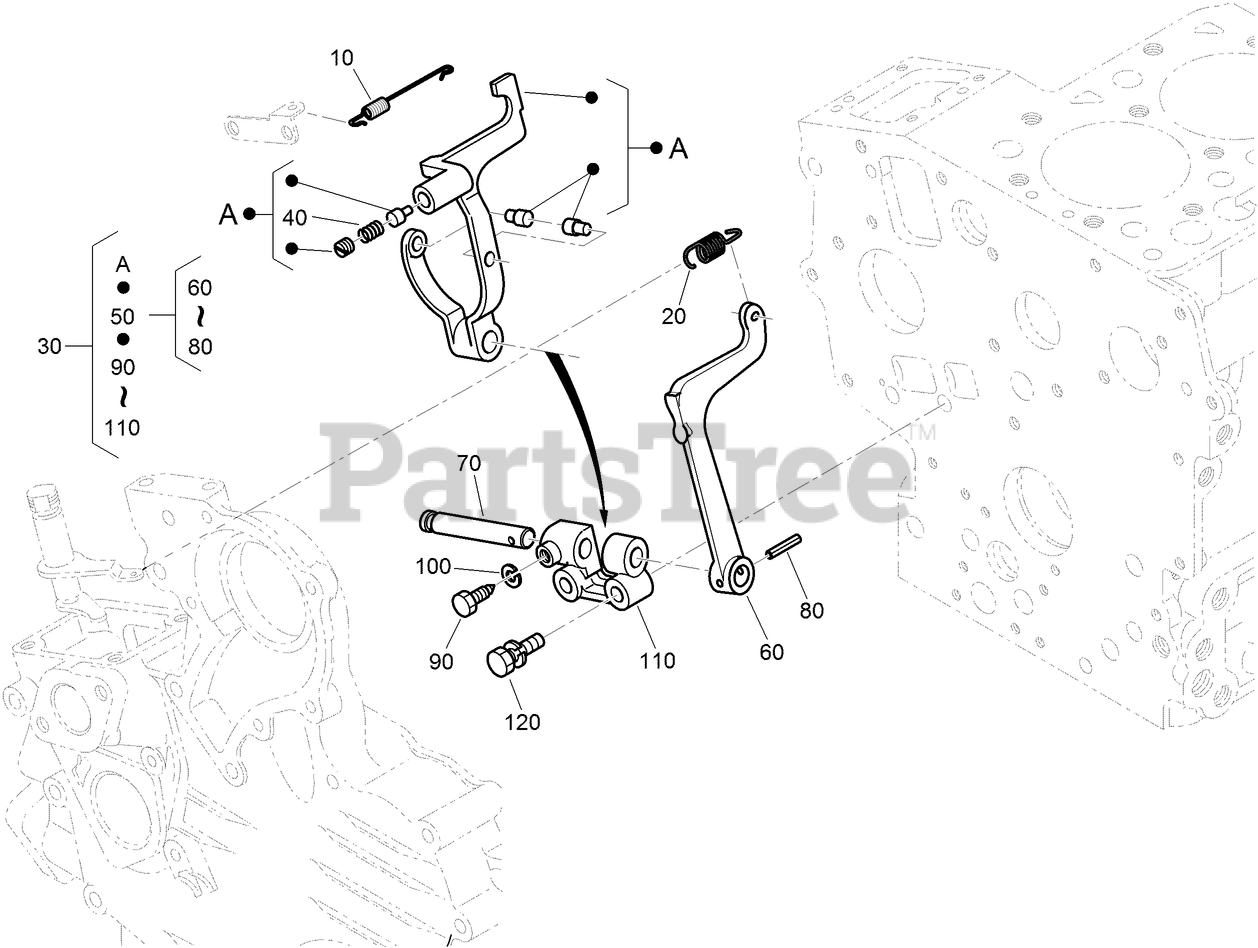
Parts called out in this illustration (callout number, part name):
10	SPRING-START
20	SPRING-GOVERNOR
30	FORK LEVER ASM
40	SPRING
50	FORK LEVER ASM
60	LEVER-FORK
70	SHAFT-LEVER, FORK
80	PIN-SPRING
100	WASHER-LOCK, SPRING
110	HOLDER-LEVER, FORK
